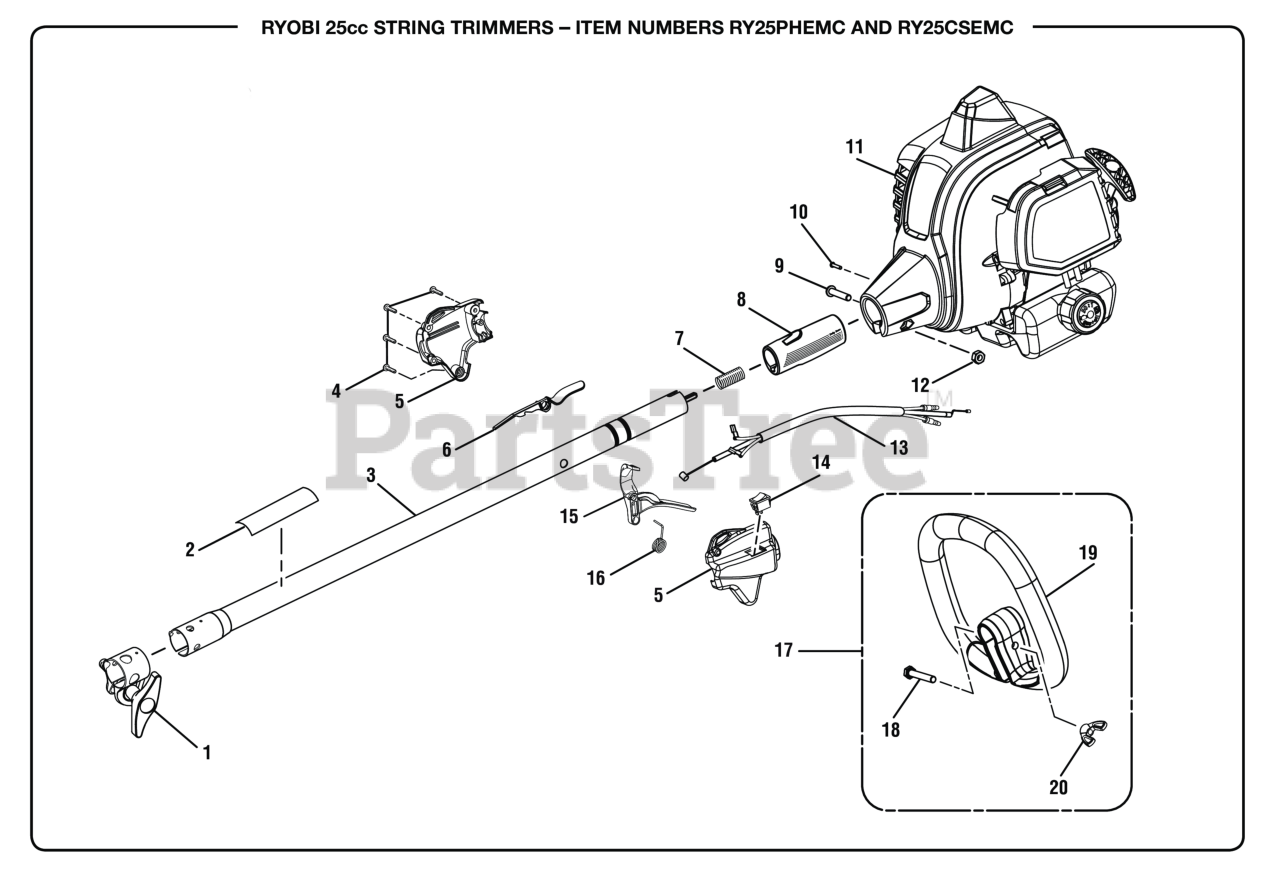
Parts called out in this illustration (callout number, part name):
1	Boom Clamp Assembly
2	Warning Icon Label
3	Upper Boom Assembly
4	Screw (M4 x 20 mm, T20 Torx Pan Hd. S.T.)
5	Control Handle Assembly (Inc. Key No. 6)
6	Trigger Lock
7	COMPRESSION SPRING
8	Rear Handle Grip
9	Screw (M6 x 30 mm, T27 Torx Button Hd.)
10	Screw (M4 x 8 mm, T25 Torx Pan Hd. T.F.)
11	Powerhead Assembly w/Labels
12	Hex Nut (M6.3 x 1)
13	Throttle Cable and Wire Assembly
14	Stop Switch (Momentary Contact)
16	Torsion Spring (Throttle Trigger)
17	Auxiliary Handle Assembly
18	Screw (1/4-20 x 40 mm, Cap Hex Hd.)
19	Front Handle
20	Wing Nut (1/4-20, Plastic)
